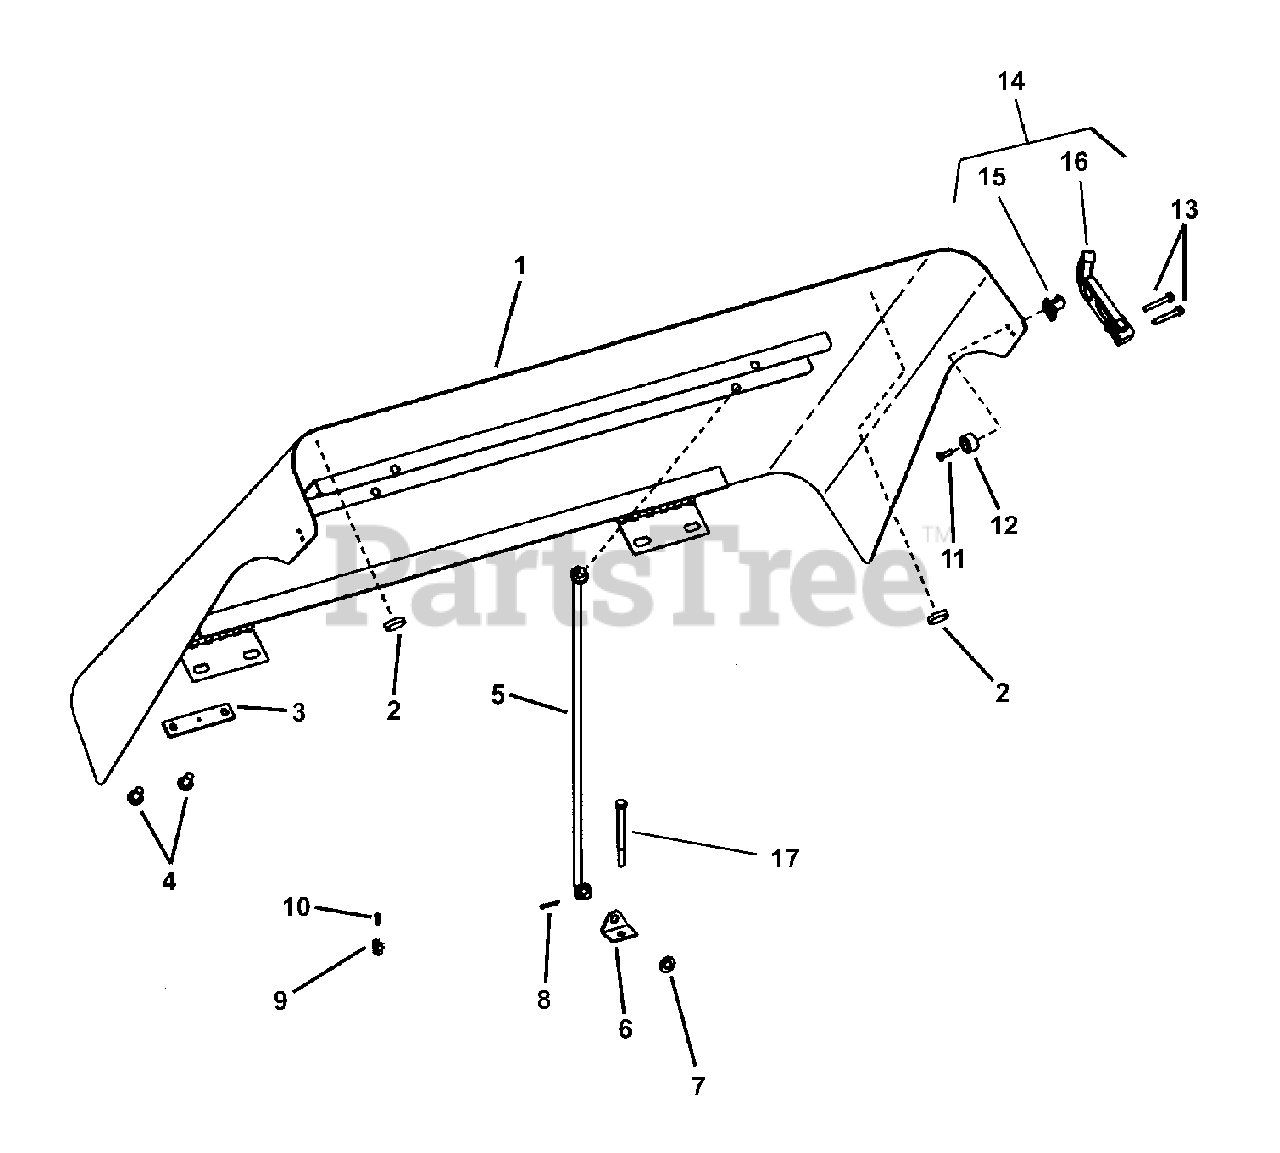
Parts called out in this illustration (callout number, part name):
1	HOOD, Utility Vehicle
2	PAD, Hood
3	PLATE WASHER
4	SCREW, Cross Recessed Pan Head, 5/16-18 x 5/8
5	PROP, Hood
6	BRACKET, Hood Prop
7	WASHER, .34 x .69 x .08 Flat
8	COTTER PIN, 3/32 x 3/4
9	HOLDER, Hood Prop
10	SCREW, Pan Head Self-Tap, #6-20 x .34
11	SCREW, Pan Head Machine, #10-24 x 1/2
12	BUMPER, Recess Style
13	SCREW, Hex Washer Self-Tap, #10 x 1-1/4, HI-LO
14	ASSEMBLY, Hood Latch (Includes Ref. Nos. 15 & 16)
15	KEEPER, Hood Handle
16	ASSEMBLY, Hood Handle
17	CAPSSCREW, Hex Head 1/4-20 x 3 GR5
